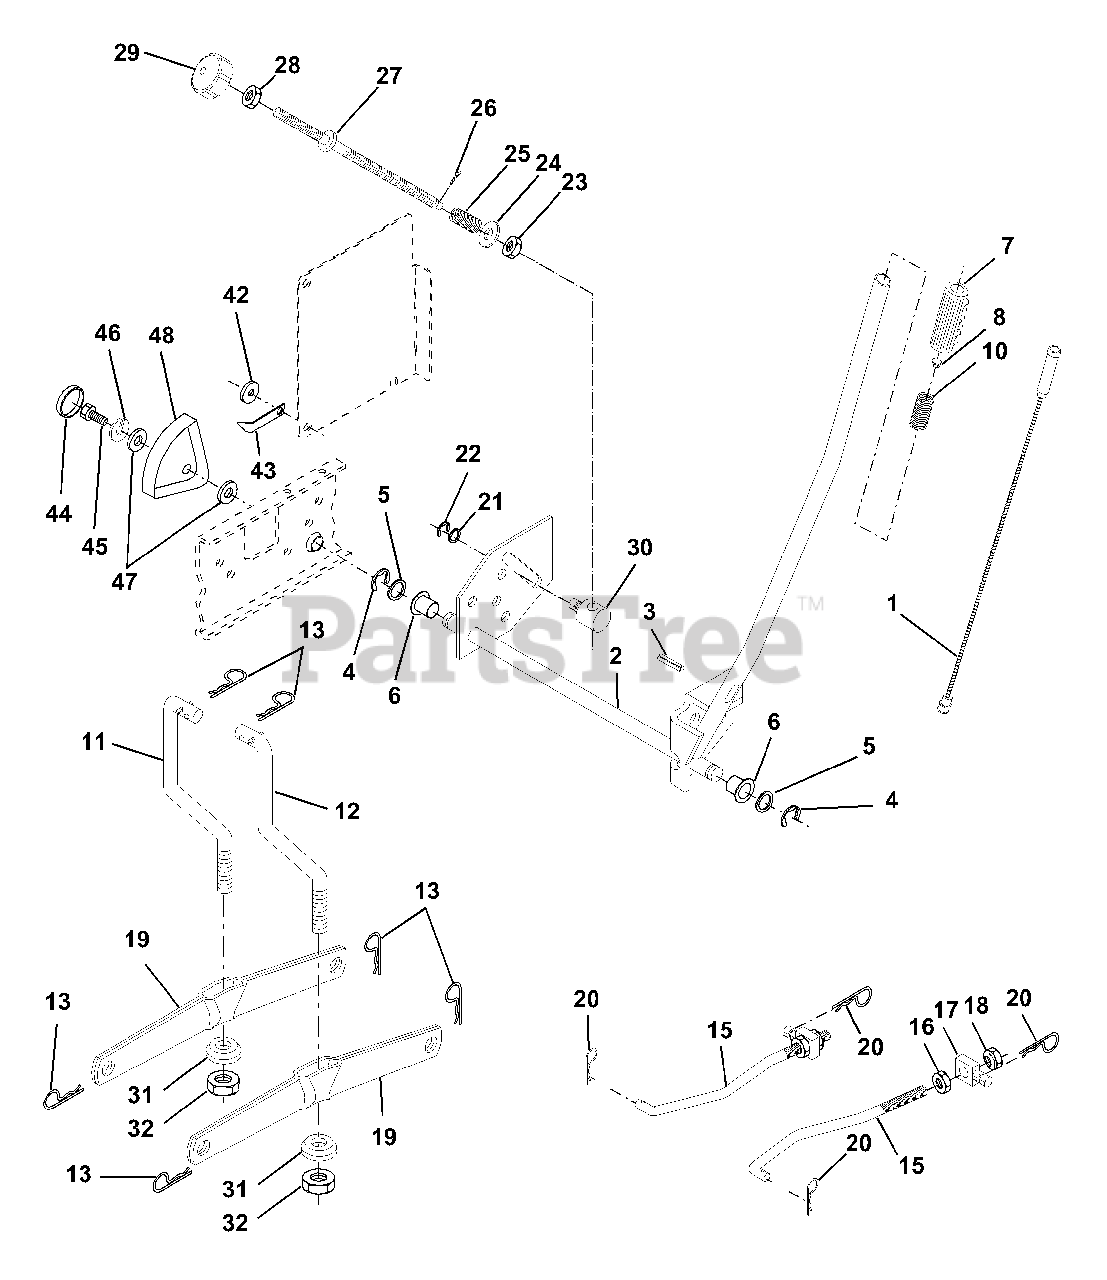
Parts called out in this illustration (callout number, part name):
1	Wire Asm Inner W/plunger 20 56
2	Shaft Asm Lift RH w/Inf
3	Pin Groove 1 500 Zinc
4	E Ring #5133-62
5	Washer 21/32 X 1 x 21 Ga
6	Bearing Nylon Blk 629 Id
7	Grip Handle Fluted Blk
8	Button Plunger Black
10	Spring Cprsn 3 750 Oiled
11	Link Lift LH
12	Link Lift RH
13	Retainer Spring
15	Link Front
16	Nut Jam Hex 1/2-13 Unc
17	Trunnion Blk Zinc
18	Nut Lock W/wsh 1/2-13unc
19	Arm Suspension Rear
20	Retainer Spring
21	Washer 15/32 X 3/4 X 16 Ga
22	Ring Klip #t5304-37
23	Nut Special
24	Washer 13/32 X 5/8 X 16 Ga
25	Spring 2-1/8"
26	Pin Cotter 3/32 X 1/2
27	Rod Adj Lift Zinc 9 00 Wrk Lg
28	Nut Hex Jam 3/8-16 Unc
29	Knob Inf 3/8-16 Unc Blk W/sym
30	Trunnion Dp Stop Dbl Thds PLT
31	Bearing Pvt Lift Spherical
32	Nut Lock 3/8-24 w/Nylon Insert
35	Washer Nylon .44 x .75 x .032
36	Pointer Height Indicator
37	Plug Hole Blk 1.485/1.515
38	Screw Thdrol 5/16-18 x 3/4
40	Washer 11/32 x 1-1/2 x 10 Ga.
41	Scale Ind. Height Blk
